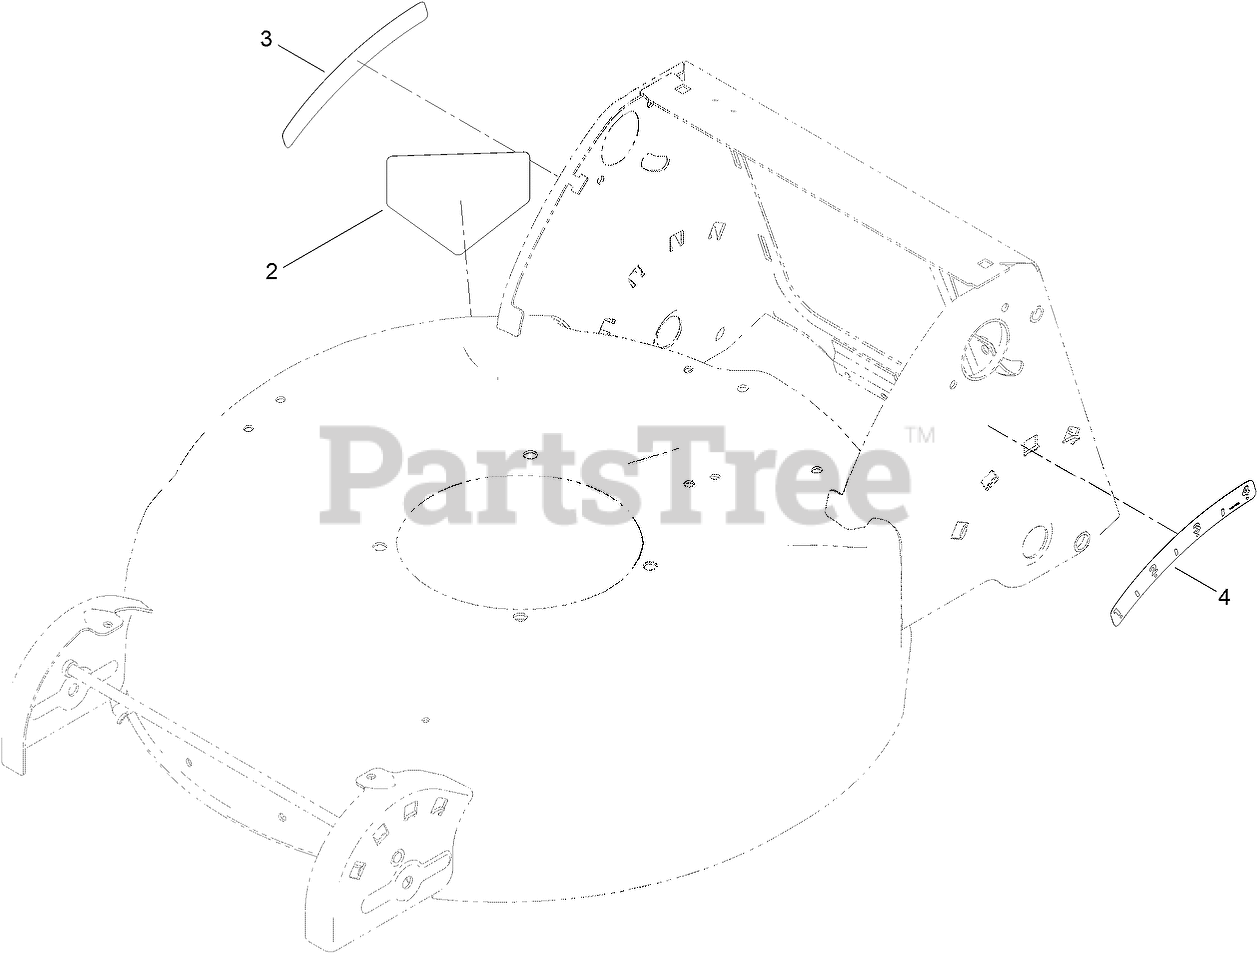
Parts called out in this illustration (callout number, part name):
2	DECAL-DANGER
3	DECAL-HOC, RH
4	DECAL-HOC, LH
